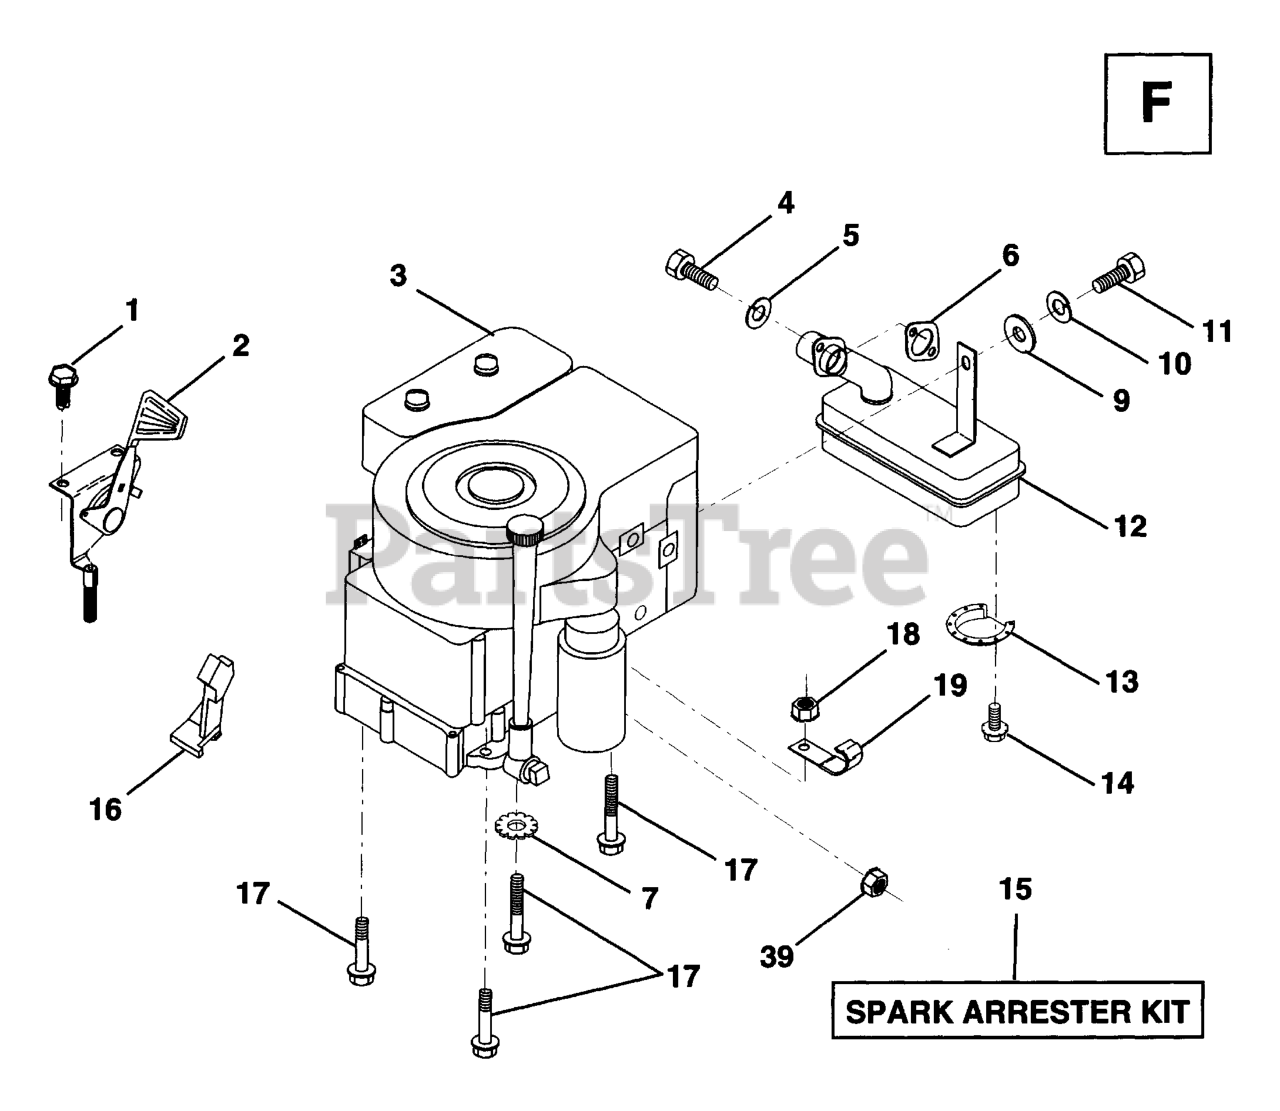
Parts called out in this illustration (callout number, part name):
2	CONTROL.TH/CH.RH.BLK.FLG.EEC
4	SCREW
5	WASHER.LOCK.HVY.HLCL.SPR.5/16
6	GASKET ENGINE
7	LOCKWASHER
9	WASHER
10	LOCKWASHER
11	BOLT.HEX.1/4.X.3/4.DICHROMATE
12	MUFFLER.SINGLE.B&S.12HP
13	DEFL MUFFLER LTV
14	SCREW
15	KIT.SPARK ARRESTOR 794945 B&S
16	STOP THROTTLE
17	SCREW LT
18	NUT.HEX.3/8-16UNC
19	CLIP T
39	NUT
